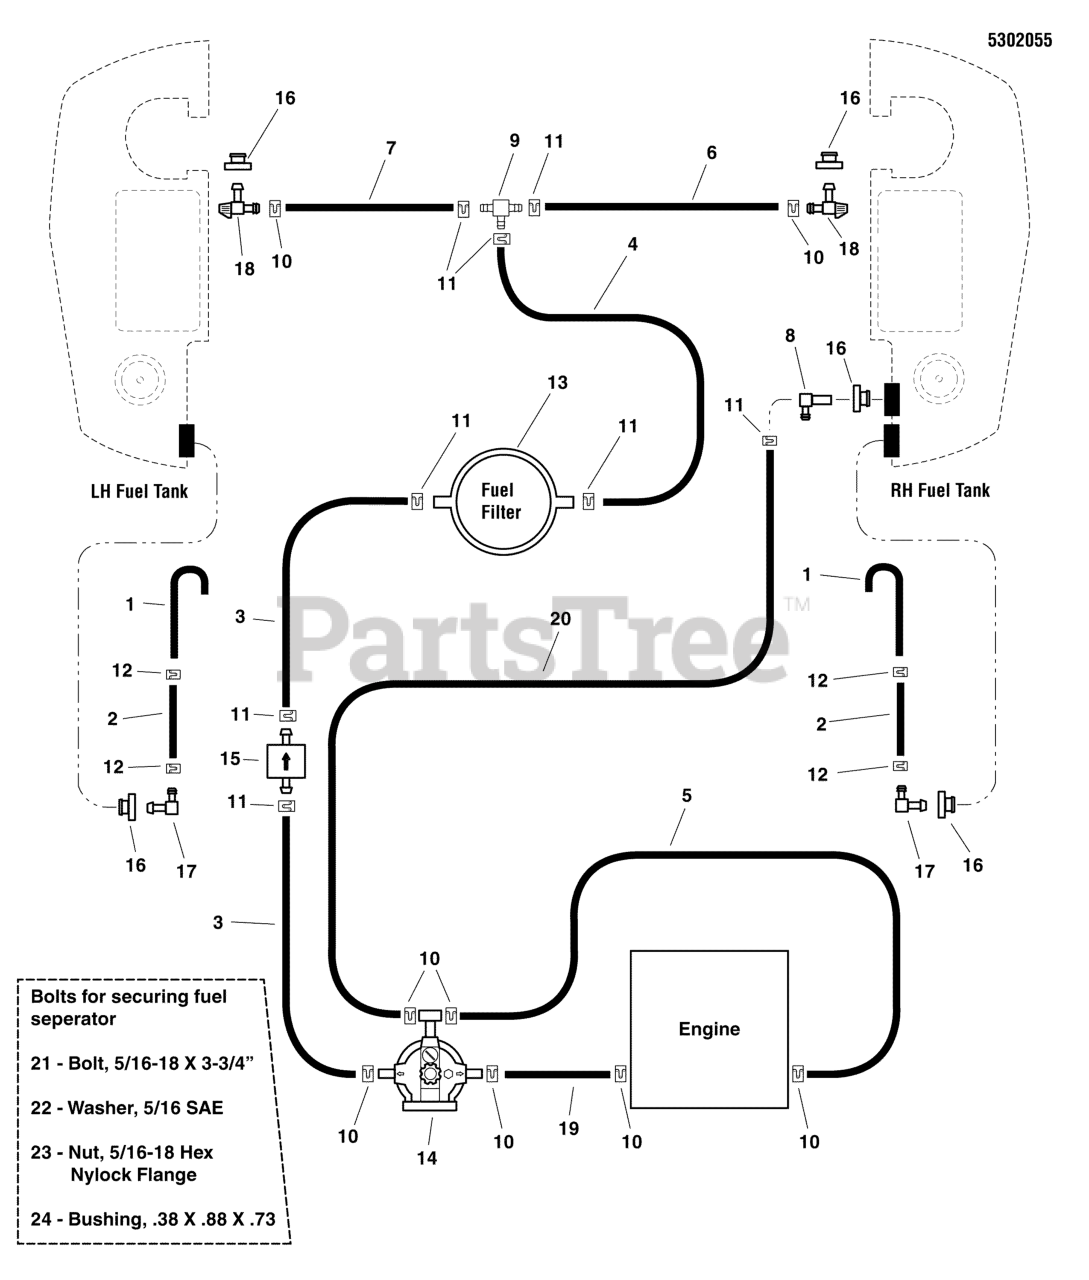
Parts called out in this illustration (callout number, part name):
1	VENT TUBE, DIESEL
2	HOSE, 1/4" FUEL, 30.00"
3	FUEL HOSE, 5/16 ID X 2.50
4	FUEL HOSE, 5/16 ID X 14.00
5	FUEL HOSE, 5/16 ID X 19.00
6	FUEL HOSE, 5/16 ID X 22.00
7	FUEL HOSE, 5/16 ID X 38.00
8	90 DEGREE ELBOW
9	FITTING, TEE, 5/16 HOSE
10	CLAMP, #4 HOSE, STAINLESS
11	CLAMP, HOSE, EXTERNAL, 9/16
12	CLAMP, HOSE, EXTERNAL, 1/2 - RED
13	STRAINER, FUEL (IN-LINE)
14	ASSY, FUEL FILTER/WATER SEP.
15	PUMP ASSY, FUEL FEED
16	BUSHING-FUEL TANK RED RUBBER
17	FITTING, DAPCO, 3/8" 90 DEGREE
18	VALVE, FUEL SHUT-OFF, 11408
19	FUEL HOSE, 5/16 ID X 17.00
20	FUEL HOSE, 5/16 ID X 25.00
21	BOLT, 5/16-18 X 3-3/4 GD5
22	WASHER, 5/16" SAE
23	NUT, 5/16-18 HEX NYLOCK FLANGE
24	BUSHING, .38 X .88 X .73
